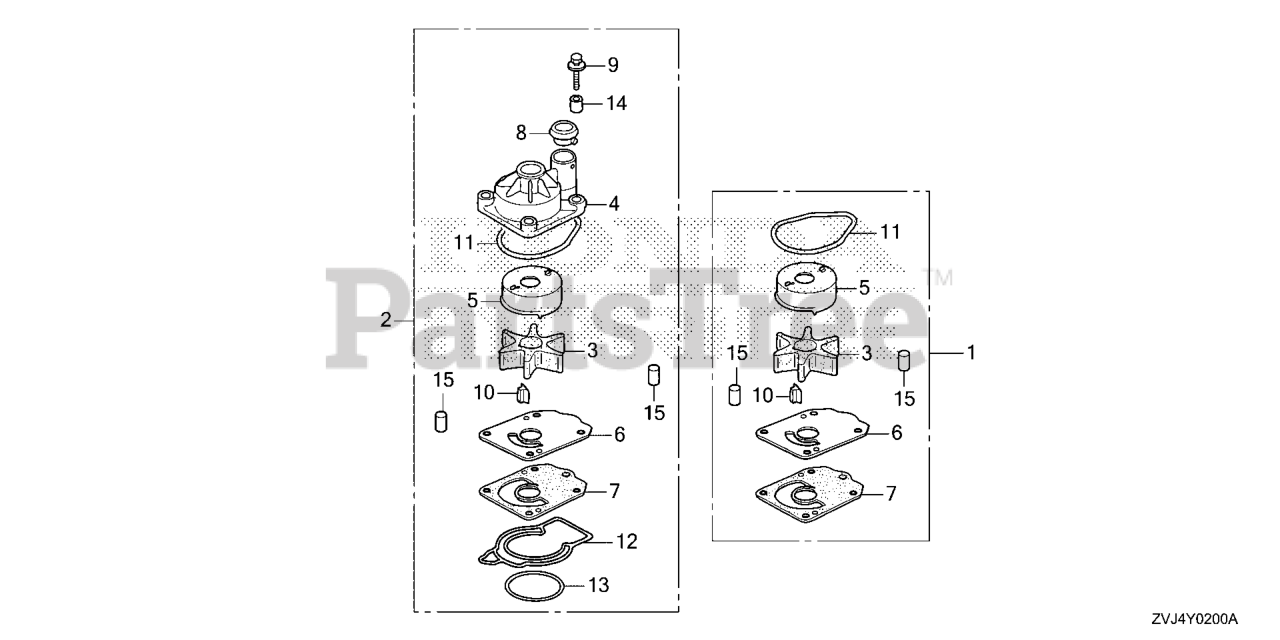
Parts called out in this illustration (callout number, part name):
1	PUMP KIT, IMPELLER
2	PUMP KIT, IMPELLER
3	IMPELLER, PUMP
4	HOUSING, IMPELLER
5	LINER, PUMP
6	COVER, IMPELLER
7	GASKET B, IMPELLER
8	RING, WATER TUBE SEAL
9	BOLT-WASHER (8X60)
10	KEY, WOODRUFF
11	O-RING, WATER PUMP
12	O-RING, WATER PUMP HOUSING
13	O-RING (65.4X2.4)
14	COLLAR, DISTANCE
15	PIN, DOWEL (6X10)
